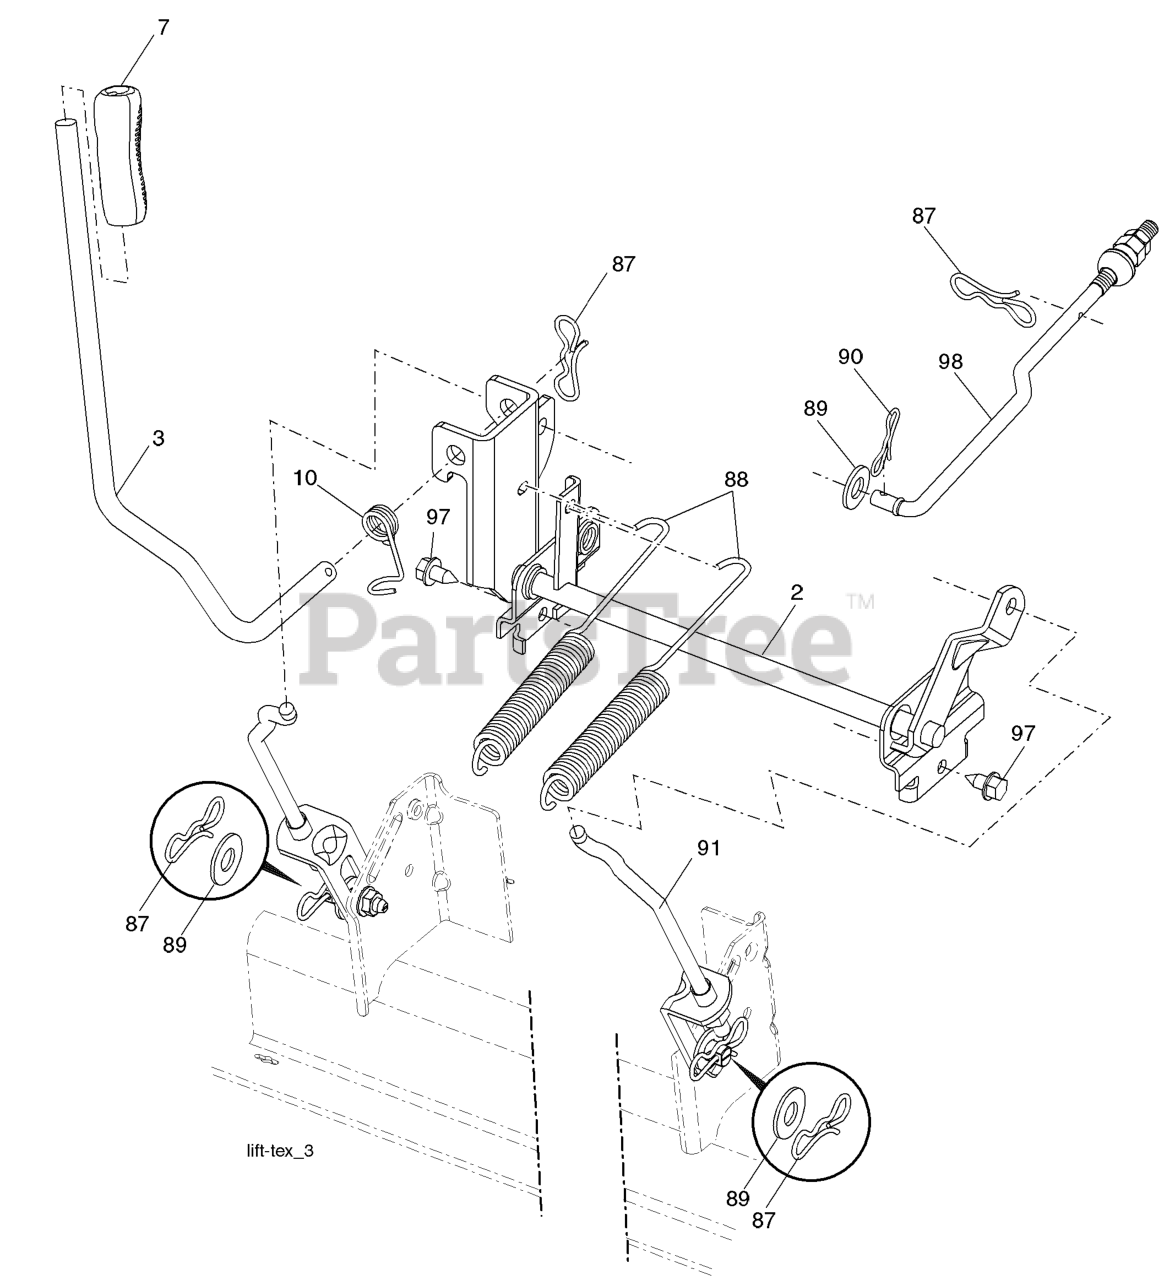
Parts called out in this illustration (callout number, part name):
2	SHAFT.ASM.LIFT.CROSS.H
3	LEVER.LIFT.HANDLE.GT
7	GRIP.HANDLE.LIFT.PVC.BLACK
10	SPRING.TORSION.LIFT.HANDLE
87	PIN.COTTER.7/16.BOW TI.
88	SPRING.LIFT.ASSIST.GT2
89	WASHER.CLEAR.ZINC
90	PIN.COTTER.5/16.BOW TI
91	LINK.ASM.LIFT.54"TG
97	SCREW 3/8-16X3/4
98	LINK.ASM.SUSP.FRONT.MWR.10.5
